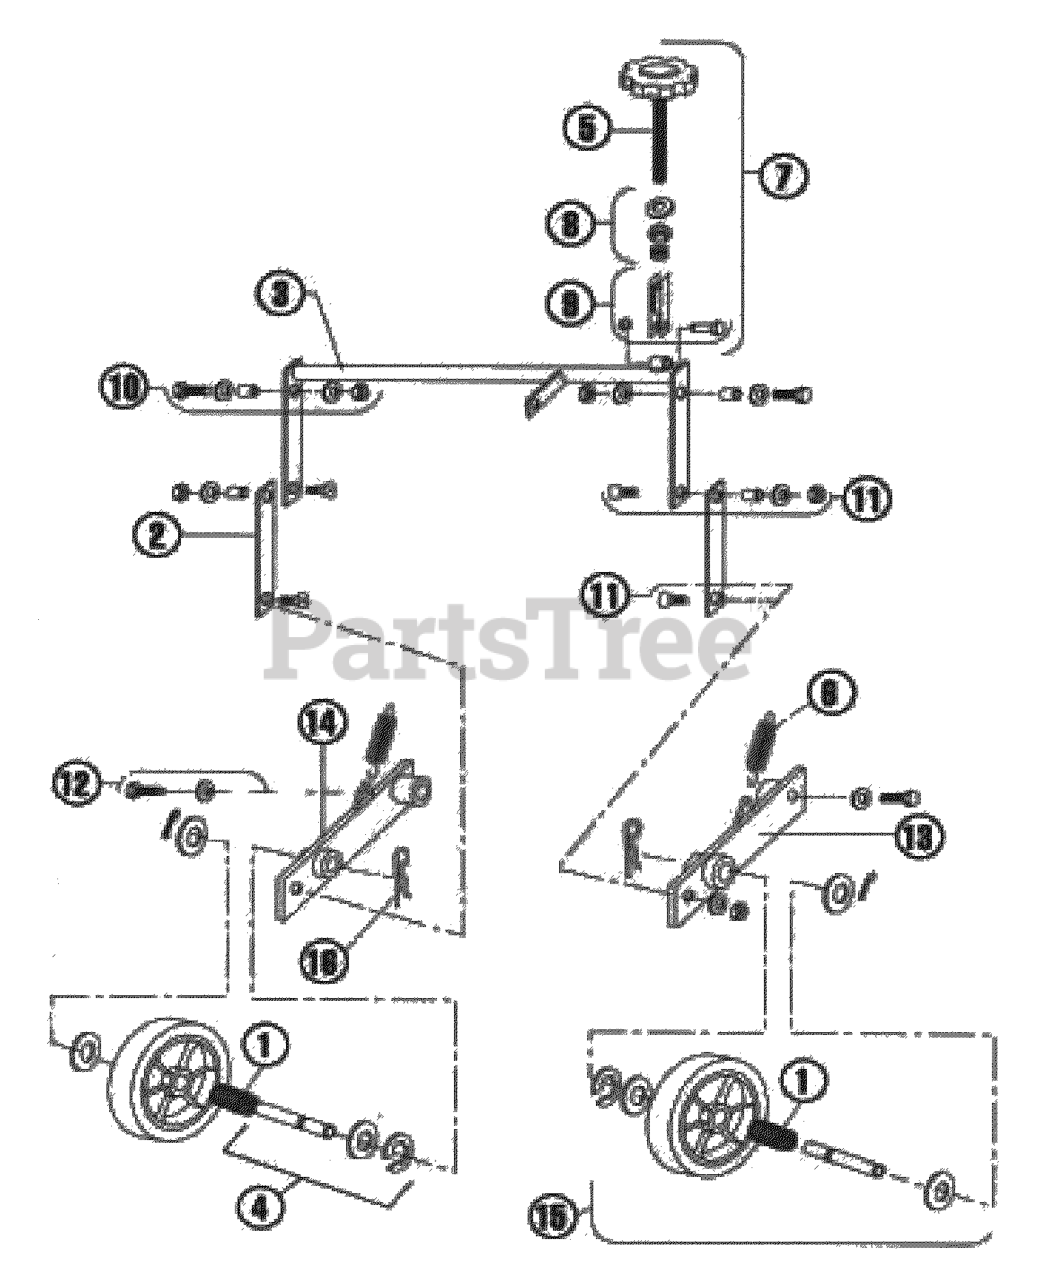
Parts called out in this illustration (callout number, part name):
1	BEARING, ROLLER
2	LIFT ARM LINK LWR ORN
3	KIT, TORQUE ARM
4	AXLE KIT
5	KNOB, DEPTH/STABILITY
6	SPRING, IDLER CAM, 3 3/4"
7	KIT DEPTH CONTROL STABILITY
8	KNOB SPRING KIT
9	BRACKET KIT
10	FASTENER KIT
11	FASTENER KIT, LINKAGE
12	FASTENER KIT
13	WHEEL ARM
14	WHEEL ARM
15	REAR WHEEL, COMPLETE
16	COTTER KEY
